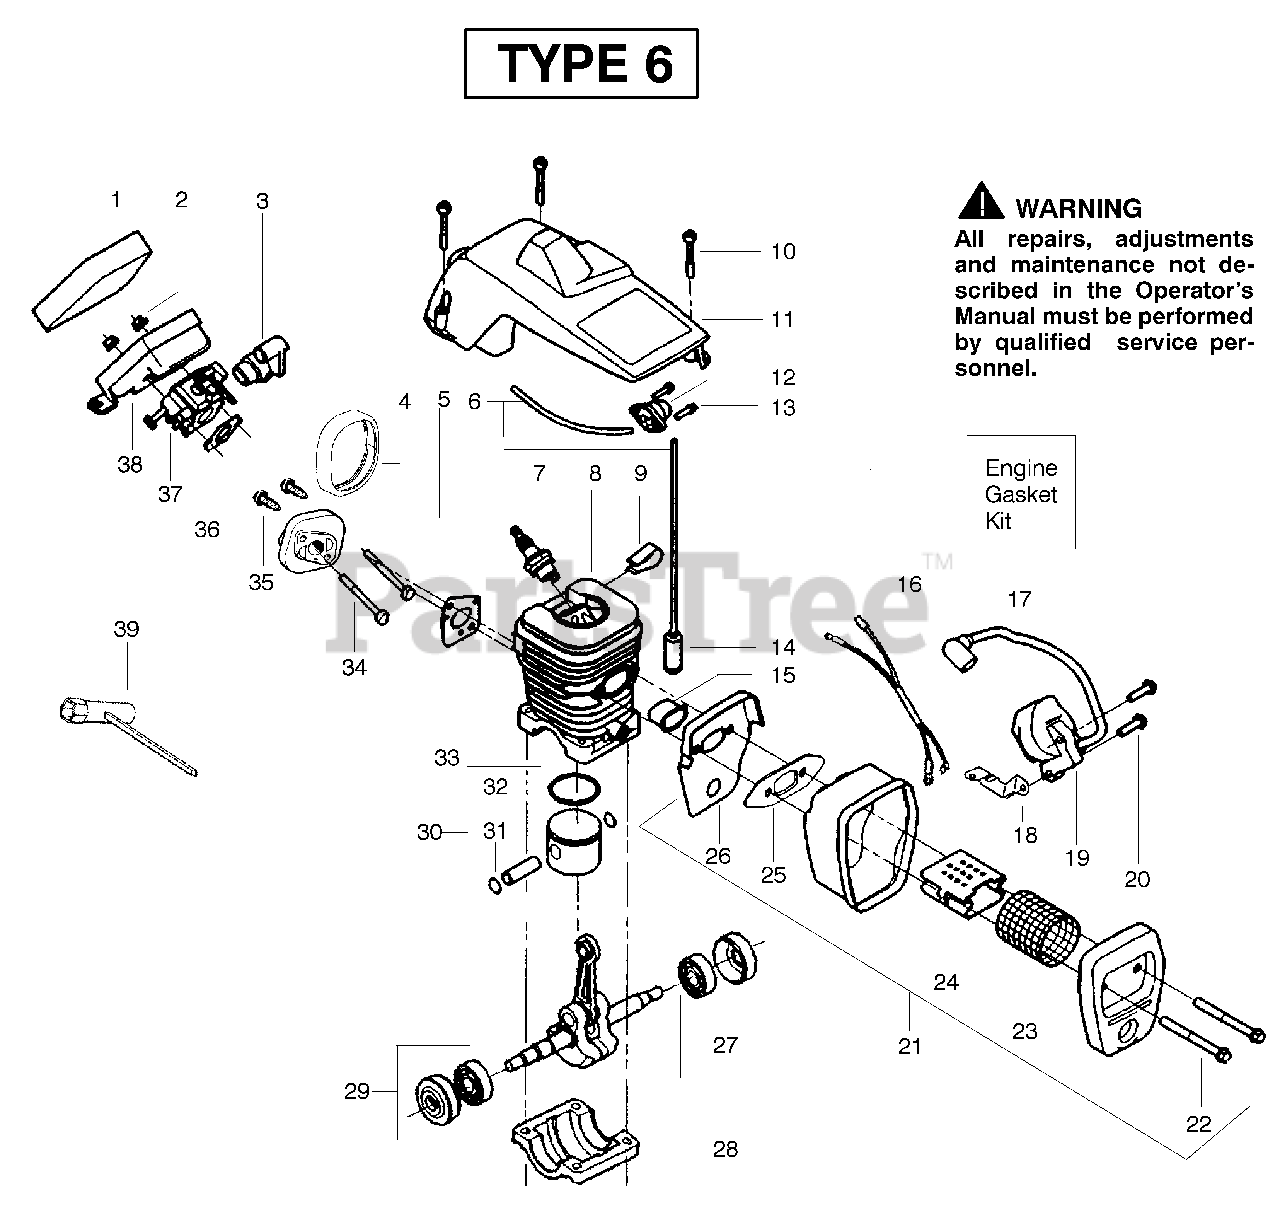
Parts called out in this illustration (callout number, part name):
1	Foam- Air Filter
3	Grommet-Carb Adjust
4	Seal-Carb Adapter
5	Carb. Adapter
6	Fuel Line Kit
7	Spark Plug
8	Kit-Cylinder
9	Clip-High Tension Lead
11	Cylinder Shield
12	Air Purge Ass’y.
14	Fuel Pick-up Ass’y.
15	Heat Insulator
16	Assy. - Wire Harness
17	Kit-Engine Gasket
18	Strap-Ground
19	Module- Ignition
21	Assy-Muffler
23	Screen-Spark
24	Diffuser-Muffler
25	Gasket-Muffler
26	Backplate-Muffler
27	Assy. - Crankshaft
28	Cap-Crankcase
29	Assy.-Seal & Bearing
30	Kit-Piston
31	Retainer-Piston Pin
32	Ring - Piston
33	Gasket-Carb. Adap.
36	Gasket - Carb.
37	Kit-Carburetor
38	Housing- Air Filter
39	Wrench - Bar
